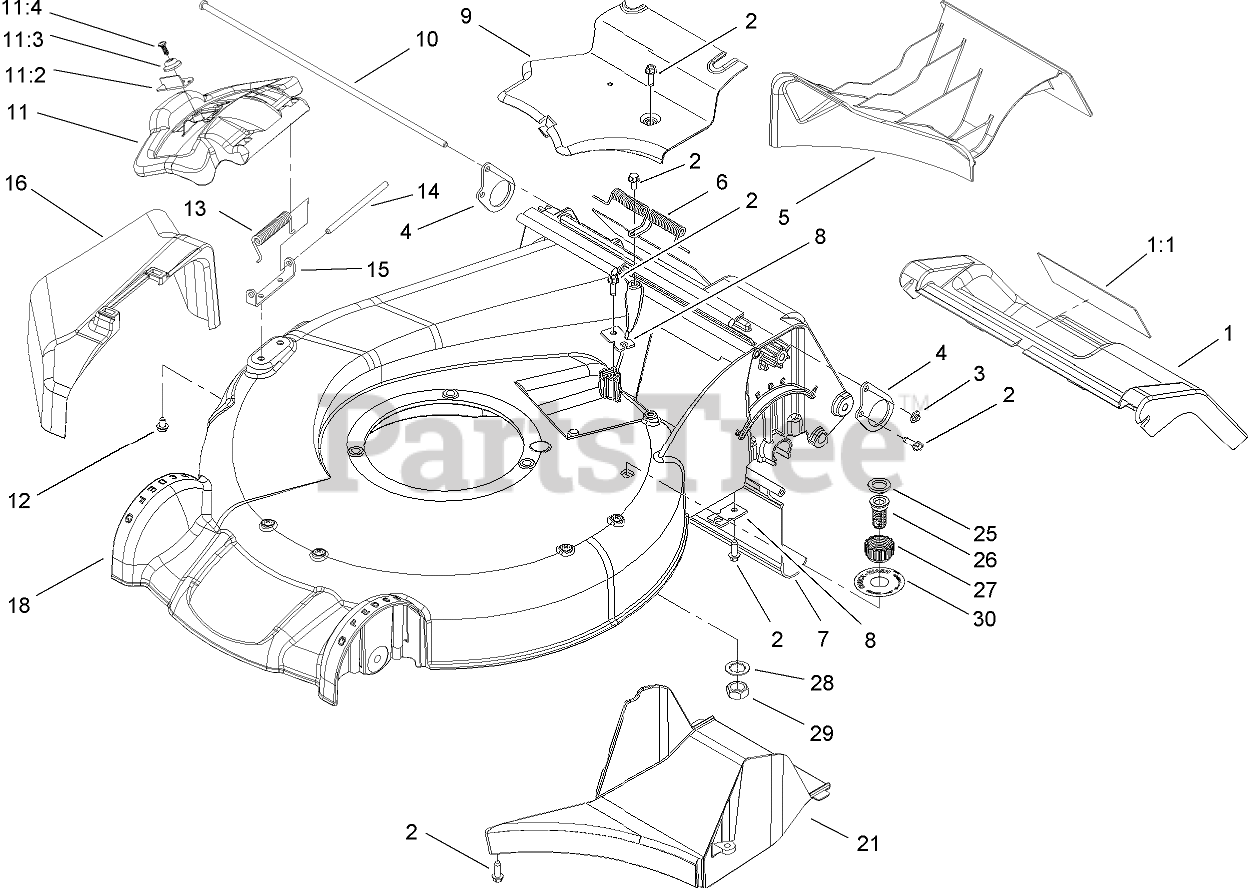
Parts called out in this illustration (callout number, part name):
1	DOOR-SERVICE
1:1	DECAL-WARNING
2	SCREW-HWHTF
3	NUT-SPEED
4	PLATE-SUPPORT, DOOR
5	MULCH PLUG ASM
6	Spring-Door, Rear
7	SHIELD-TRAILING
8	BRACKET-CABLE, TRACTION
9	COVER-BELT
10	ROD-SUPPORT, DOOR
11	DISCHARGE DOOR ASM
11:2	LATCH-DOOR
11:3	CAP-DOOR
11:4	SCREW-PLASTITE
12	SCREW-HWH
13	SPRING-TORSION
14	ROD-COVER
15	BRACKET-COVER
16	CHUTE-DISCHARGE, SIDE
18	HOUSING ASM
21	TUNNEL-DISCHARGE
25	WASHER-SEAL, WASHOUT PORT
26	PORT-WASHOUT
27	COUPLING-HOSE, WASHOUT PORT
28	WASHER-TOOTH, INTERNAL
29	NUT-JAM
30	DECAL-WASHOUT PORT
